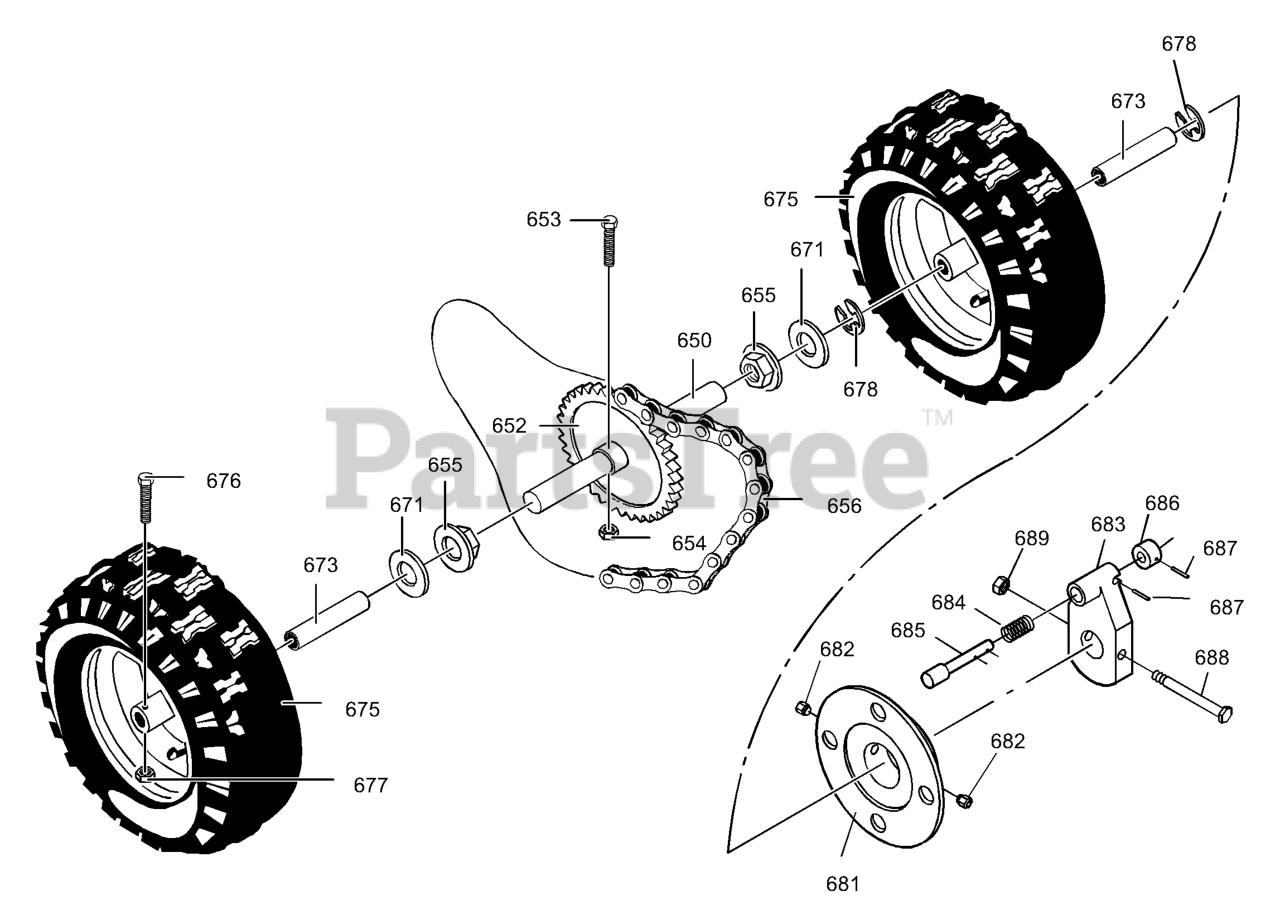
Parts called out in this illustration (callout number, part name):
650	SHAFT, AXLE
652	SPRKT & HUB
653	SCREW, 1/4-20X2.25
654	NUT, 1/4-20 HEX NYLOCK
655	RETAINER, BEARING
656	CHAIN, ROLLER
671	FLATWASHER
673	BUSHING, WHEEL
675	TIRE & RIM
676	SCREW, 1/4-20X1.75
677	NUT, 1/4-20 HEX NYLOCK
678	RING, RET
681	DISC, WHEEL
683	HUB, WHEEL LOCK
684	SPRING, COMPRESSION
685	PIN, LOCK
